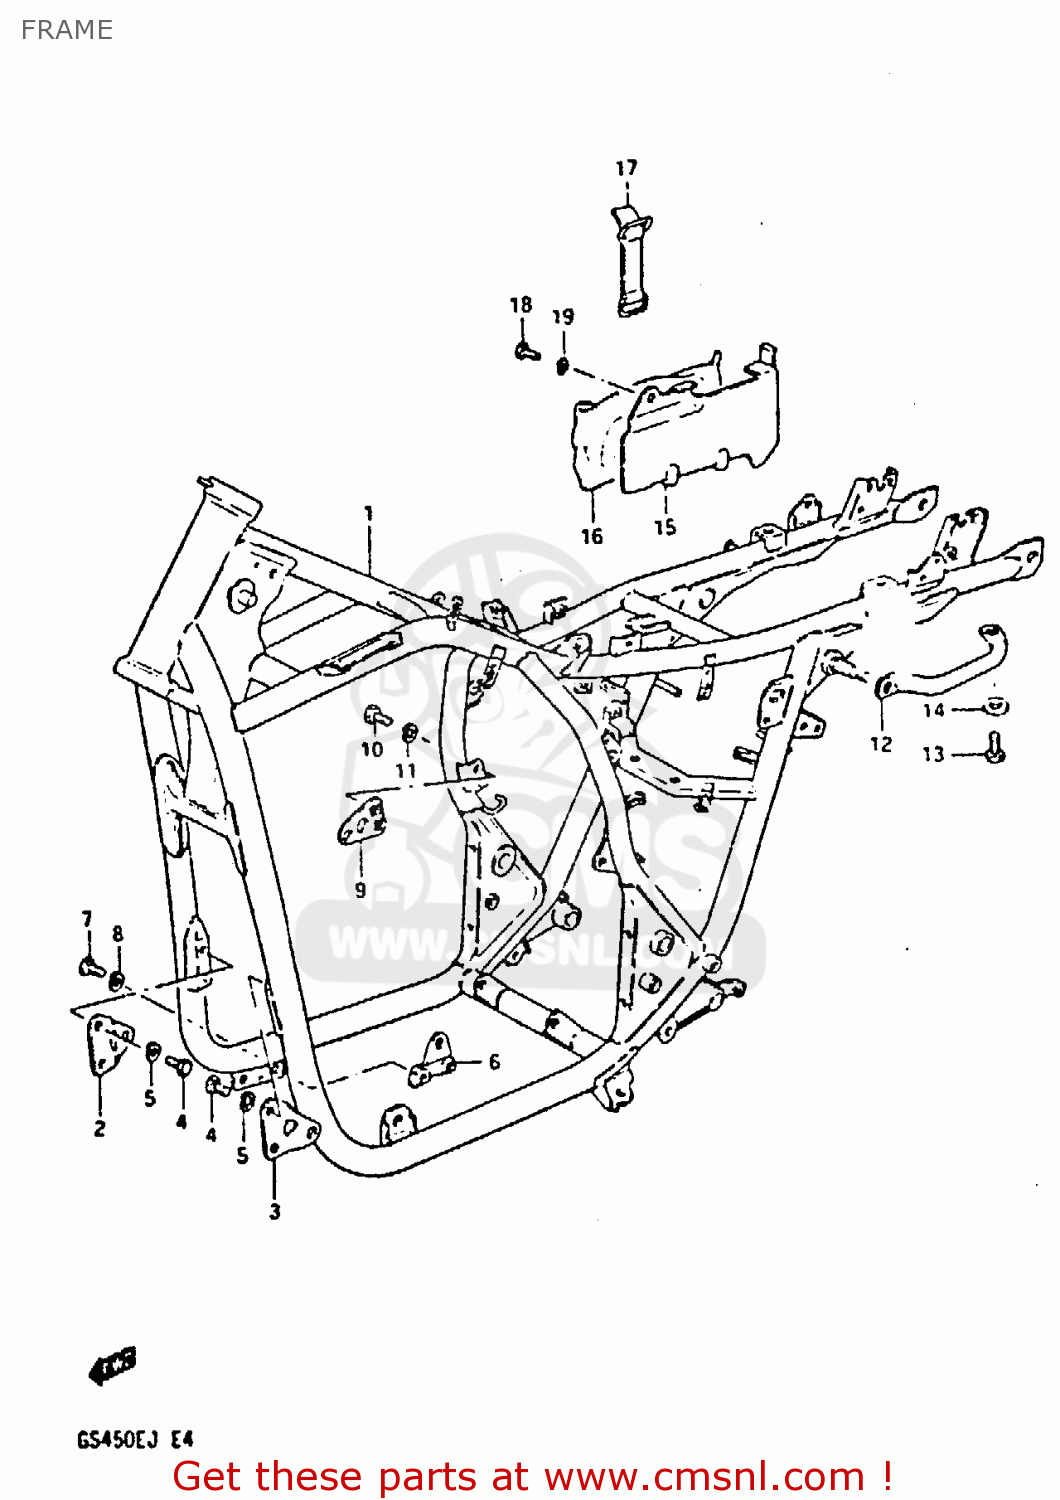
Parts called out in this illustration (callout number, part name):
1	FRAME (BLACK)
2	PLATE,ENG MTG NO.1,R
3	PLATE,ENGINE MOUNTING,LEFT
4	BOLT
5	WASHER,LOCK,8.
6	PLATE,MOUNTING NO.2,LEFT
7	BOLT
8	WASHER,LOCK,8.
9	PLATE,MOUNTING NO.4,LEFT
10	BOLT
11	WASHER,LOCK,8.
12	GRIP,FRAME HANDLE
13	BOLT,8X16
14	WASHER
15	HOLDER,TOOL
16	TOOL SET
17	BAND
18	BOLT
19	WASHER,LOCK
